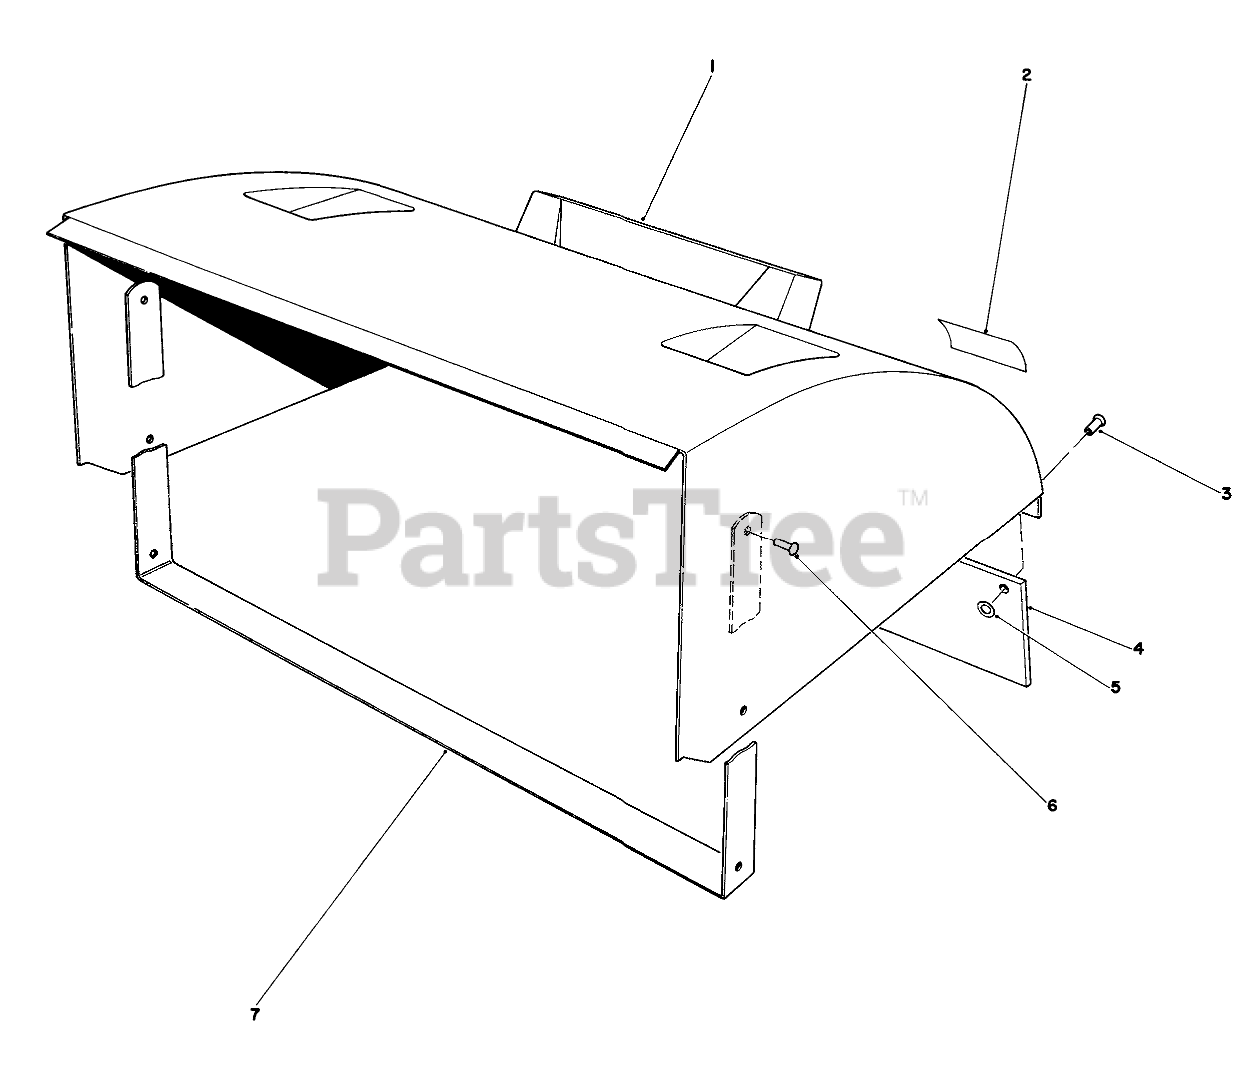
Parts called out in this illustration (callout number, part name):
1	Deflector-Grass
2	Decal Danger
3	.185 DIA X .375 RT +
4	Flap-Deflector
5	WASHER-FLAT
6	RIVET
7	Bracket-Grass Deflector
